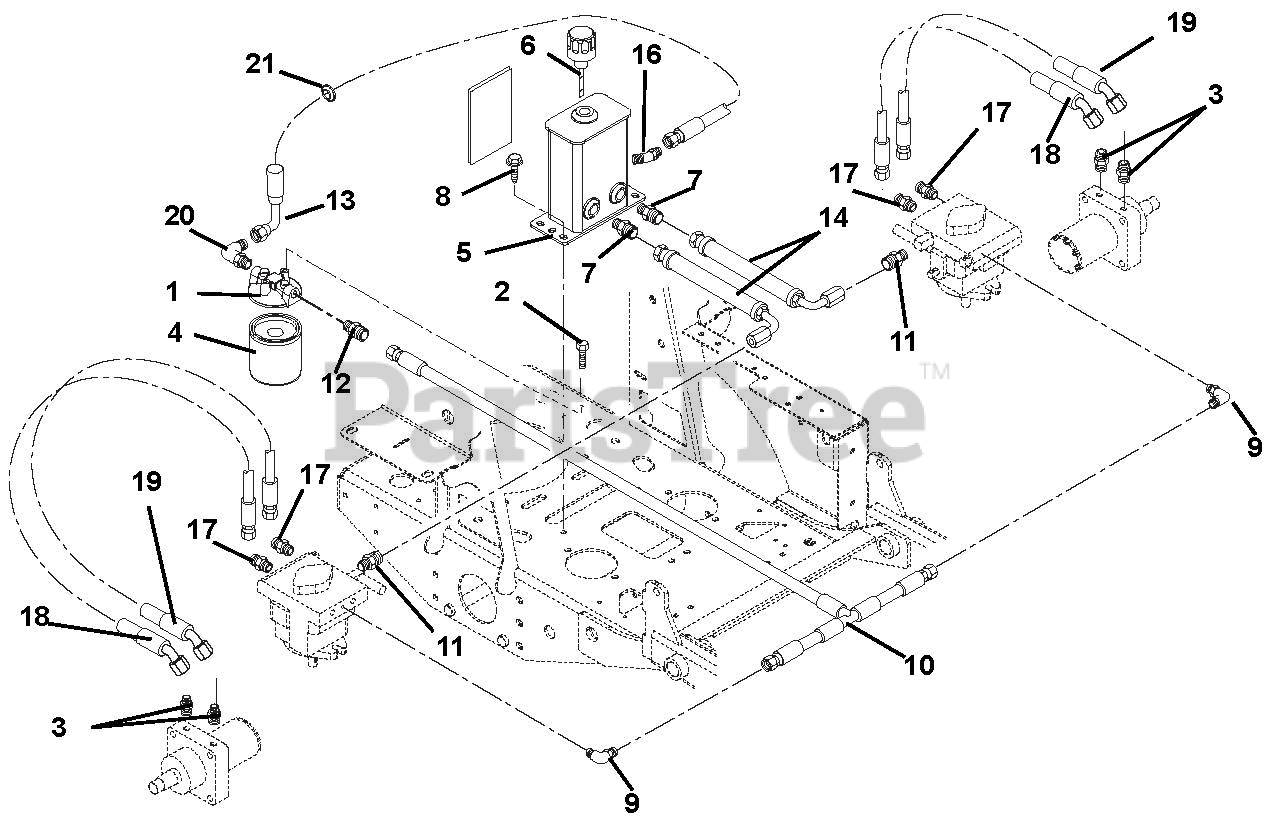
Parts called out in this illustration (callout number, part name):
1	Head, Filter
2	Bolt, Hex .25-20 x .50 Grade 5
3	Adapter, Hydraulic
4	Oil Filter
5	Tank, Hydraulic
6	Breather Dipstick
7	Fitting, Hydraulic Straight M8O-M4F
8	Screw, Tapping .38-16 x .50 Hex Washer Head
9	Adapter, Hydraulic 8MB-12FPX90
10	Hose, Tee Assembly without Auxiliary .38
11	Fitting, Hydraulic (4-6 F5OLO)
12	Fitting, Hydraulic (6 F5OLO)
13	Hose, Hydraulic .38-9-0K F6F0-F6F9
14	Hose, Hydraulic
15	Shield, Heat 5.50 x 4.50
16	Fitting, Hydraulic 45 Degree M6F-M80
17	Fitting, Hydraulic
18	Hose, Hydraulic .50-11-3K
19	Hose, Hydraulic .50-12-3K
20	Fitting, Adapter 8MB-12FPX90
21	Grommet, 1.25ID x 1.50OD
